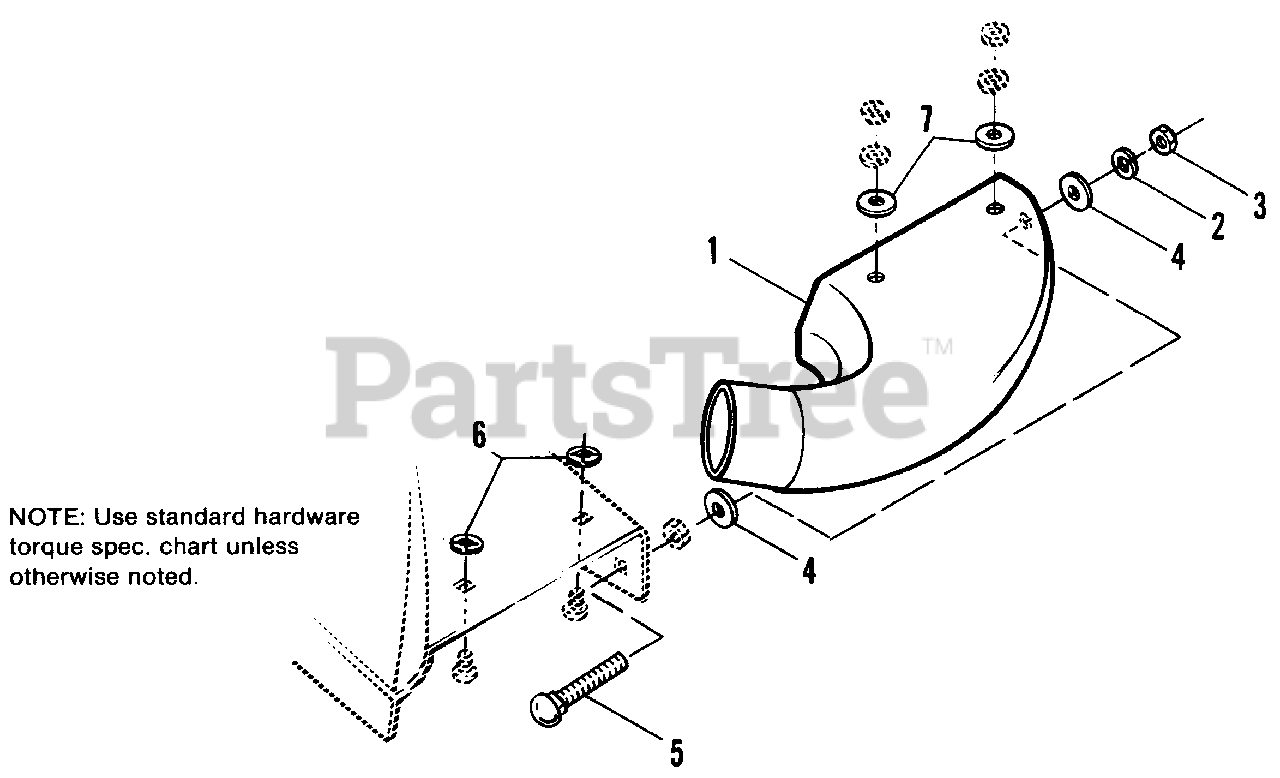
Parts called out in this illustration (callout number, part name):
1	ADAPTOR, 42" & 48" Mowers
2	LOCKWASHER, Spring, 5/16
3	NUT, Hex, 5/16-18
4	WASHER, Plain, 5/16
5	BOLT, Carriage, 5/16-18 x 1-1/4
6	PUSHNUT, 3/8
7	WASHER
